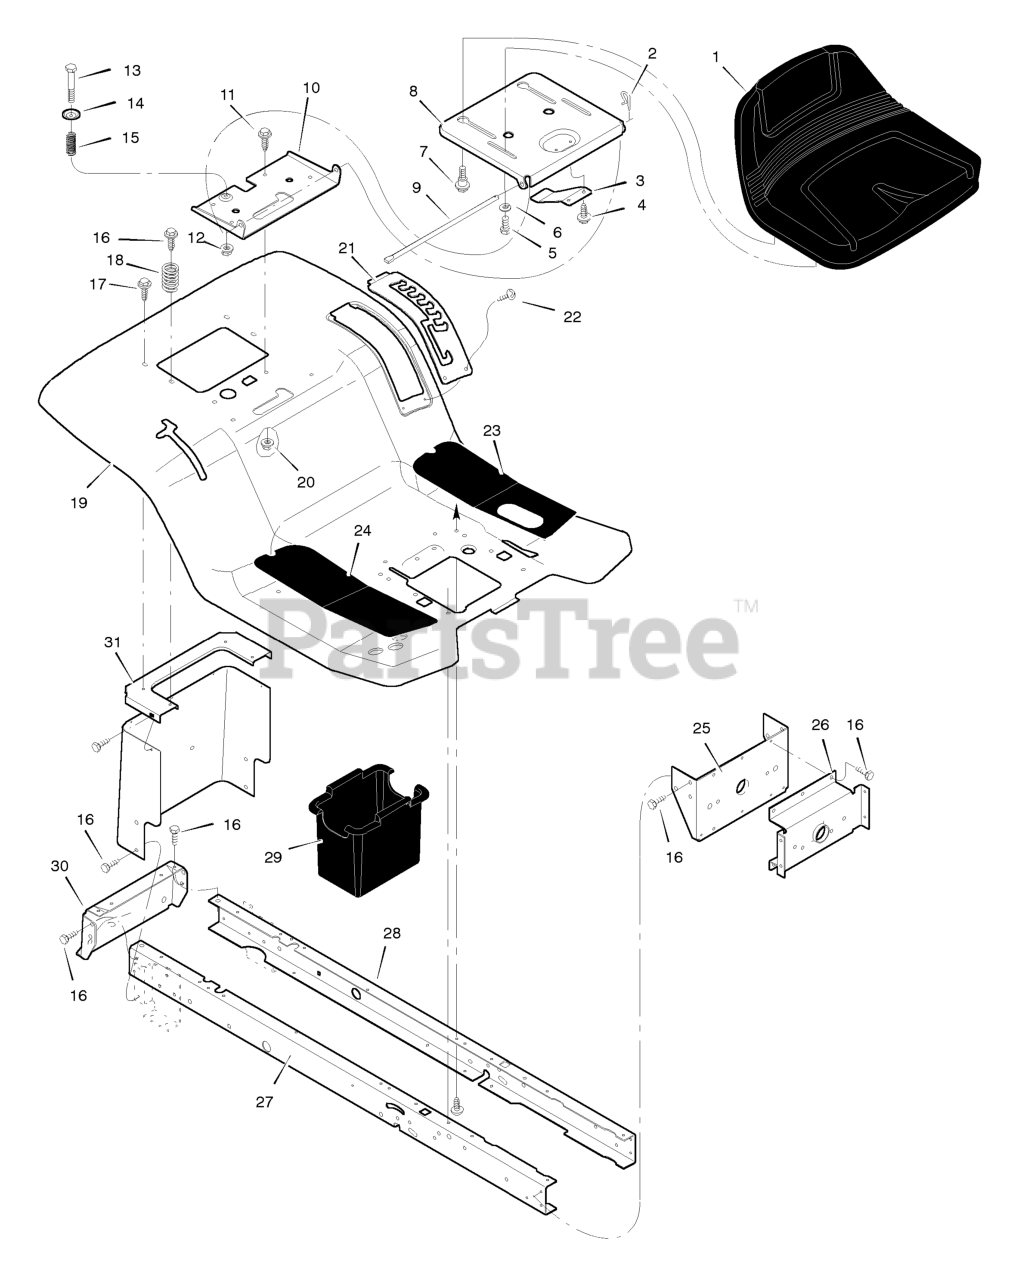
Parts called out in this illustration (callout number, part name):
2	Cap, Push On
4	Screw
5	Bolt, Wing
6	Washer
7	Bolt, Shoulder
8	Support, Seat
9	Rod, Pivot
10	Bracket, Pivot
11	Bolt
13	Bolt, Shoulder
15	Spring
19	Deck, Seat
20	Nut
21	Plate, Index
22	Screw
23	Mat, Left
24	Mat, Right
25	Bracket, Rear Hanger
26	Axle, Hanger
27	Frame, Right
28	Frame, Left
29	Container, Battery
30	Plate, Hitch
31	Panel, Rear
